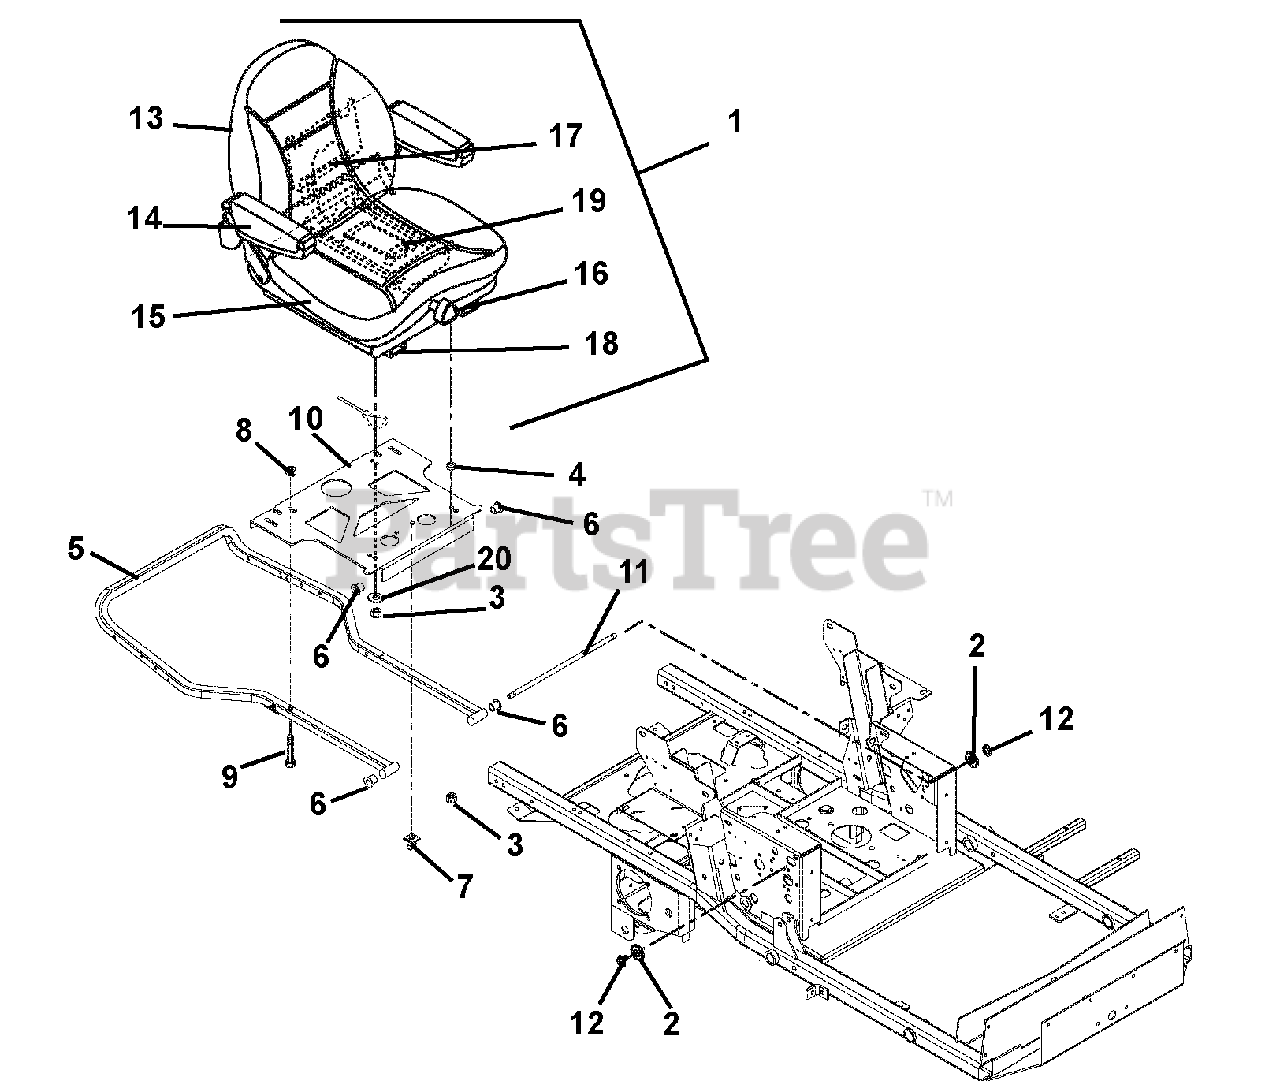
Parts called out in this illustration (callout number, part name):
1	Seat, Suspension, Light Gray
2	Washer, Flat Steel .531 x 1.06 x .095
3	Nut, Locking Top Flange .31-18
4	Bushing, Sleeve .377 x .624 x .235
5	Weldment, Hood Frame
6	Bushing-Flange .515 x .750 x .745 x 1.00
8	Nut, Locking Top Flange .38-16
9	Bolt, Rib Neck .38-16 x 1.50
10	Weldment, Seat Pivot Plate
11	Rod, Seat Frame Pivot
12	Ring, Retaining External .500 x .050
13	Kit, Back Cushion, Light Gray
15	Kit, Seat Cushion, Light Gray
16	Kit, Seat Knobs
17	Kit, Seat Back
18	Kit, Seat Slides
19	Kit, Seat, Spring and Saddle
20	Washer, Flat Steel .344 x 1.25 x .135
